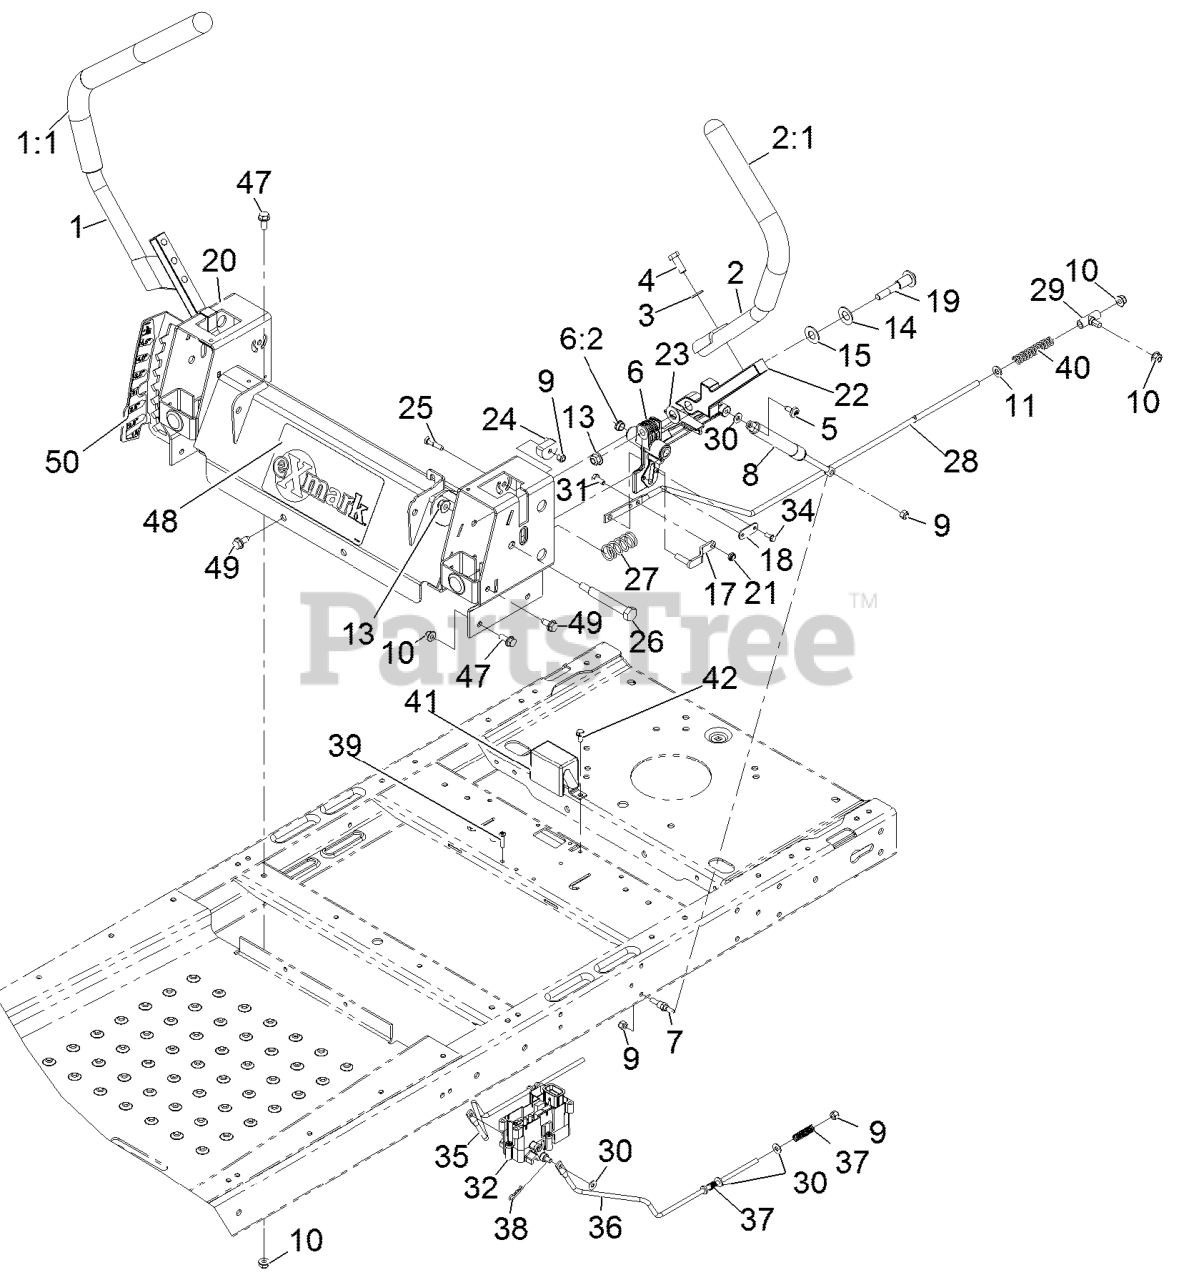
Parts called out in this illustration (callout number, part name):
1	HANDLE-CONTROL, RH
2	HANDLE-CONTROL, LH
3	WASHER-FLAT
4	SCREW-HH
5	SCREW-SHOULDER
6	ACTUATOR ARM ASM
6:2	BUSHING-FLANGE
7	STUD-DAMPER
9	NUT-LOCK, NI
10	NUT-HF, NI
11	WASHER-PLAIN
13	NUT-HF, NI
14	WASHER-BELLEVILLE
18	PLATE-STOP, HYDRO
19	BOLT-PIVOT
21	NUT-LOCK, NI
23	WASHER-NYLON
24	ECCENTRIC
25	BOLT-PIVOT, ECCENTRIC
26	BOLT-PIVOT
27	SPRING-RETURN
28	ROD-HYDRO
29	MOUNT-ROD, HYDRO
31	SCREW-HH
34	SCREW-TAPTITE
35	ROD-BRAKE, WIDE (RH)
36	ROD-BRAKE, WIDE (LH)
37	SPRING-COMPRESSION
39	SCREW-PPH
40	SPRING-RETURN, NEUTRAL
41	COVER-BRAKE
42	SCREW-HWH
47	SCREW-HHF
49	Screw-HWH 5/16-18 X 3/4 Tf
50	DECAL-HOC
